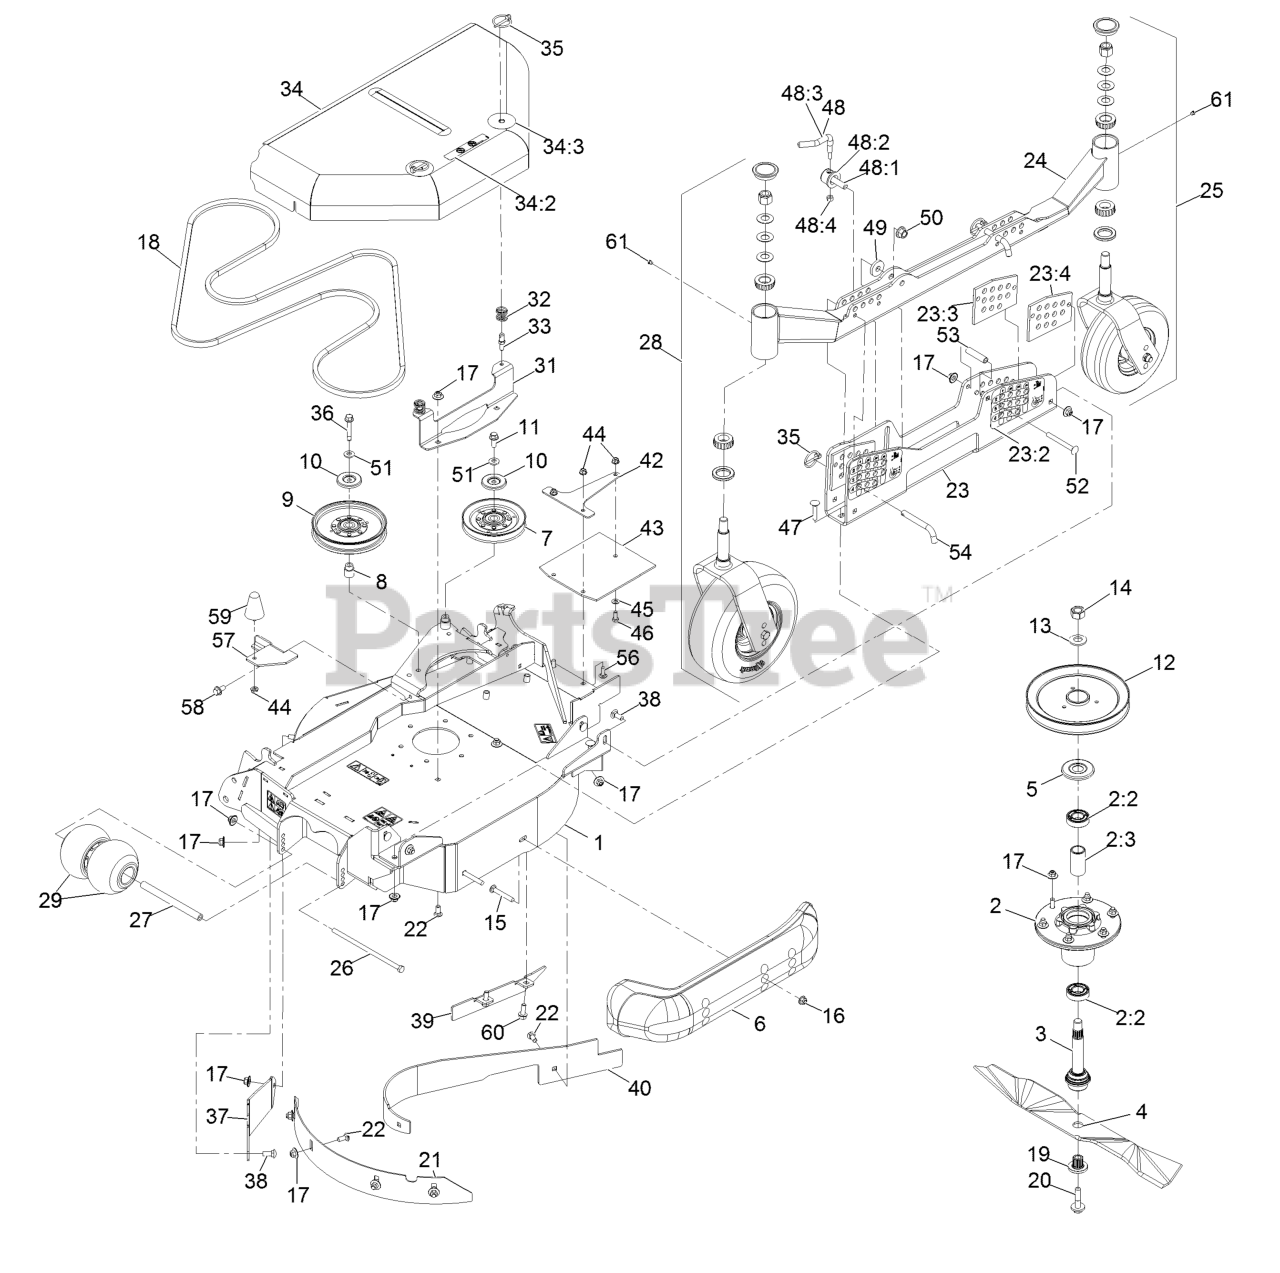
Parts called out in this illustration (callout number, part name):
1	ASM-Deck, LH Wing 96/120
2	ASM-Cutter Hsg With Bearings
2:2	Bearing-Ball
2:3	Spacer-Bearing
3	ASM-Spindle And Seal
4	Blade, Mulching
5	Guard-Bearing Top
6	Skid-Bumper, Deck
7	Idler-V
8	Bushing, Idler
9	Idler-Pulley
10	Shield-Dust
11	Screw HHF 3/8-16 X 1
12	Sheave-Single 96Rd
13	Washer-Spring Disc 3/4
14	Nut-Hex
15	Bolt-Carriage 3/8-16 X 2 1/2
16	Nut-Nyloc 3/8-16 Flg
17	Nut-Nyloc 3/8-16 Flg
19	Bushing, Splined
20	Screw-Sems 1/2-20 X 2.19
21	Baffle-Depth, LH
22	Bolt-CARR
23	LH HOC Channel ASM
23:2	Decal-Height Of Cut-LH
23:3	Plate-Guide, HOC (LH)
23:4	Plate-Guide, HOC (RH)
24	Tube-HOC, LH
25	Caster/Wheel ASM
26	Screw-HH
27	Spacer-Wheel
29	Roller-Anti-Scalp
31	Bracket-Shield Mount, Outer
33	Pin-Spring
34	LH Wing Shield ASM
34:2	Decal-No Step
34:3	Decal-Scratch Cover
35	Pin-Lynch
36	Screw-HHF W/ Patch
37	Plate-Fill, LH Deck
38	Bolt-Carriage 3/8-16 X 1
39	Fin-Baffle, Discharge Wing (LH)
40	Baffle-Dogleg, Center (RH)
42	Support-Flap, LH
43	Guard-Tire, LH
44	Nut-Nyloc 5/16-18 Flg
45	Washer-5/16 SAE
46	Screw-HH 5/16-18 X 3/4
47	Bolt-Carriage 3/8-16 X 1 3/4
48	Lever ASM
48:1	Screw-Lock
48:2	Cap-Lock
48:3	Lever-Lock
48:4	Nut-Nyloc 5/16-18
50	Nut-Lock 1/2-13
51	Washer-Spring Disc 3/8
52	Bolt-Carriage 3/8-16 X 3 1/2
54	Pin-HOC
56	Bolt-Carriage 5/16-18 X 7/8
57	Bracket-Cover Retainer
58	Screw-HWH
59	Bumper-Rubber
60	Screw-HH Flg 3/8-16 X 1
